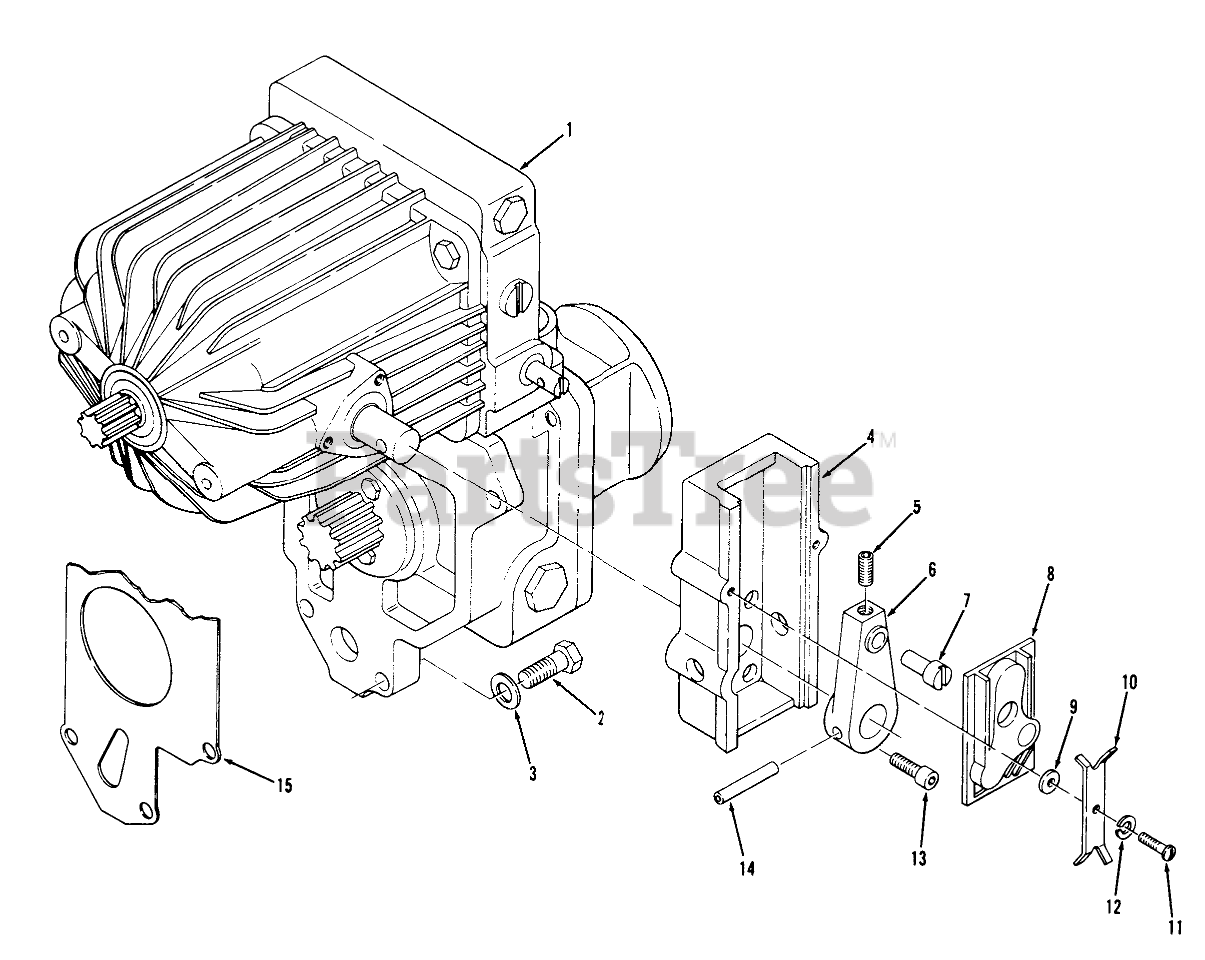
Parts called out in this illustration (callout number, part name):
1	Hydro Unit
2	BOLT
3	Washer
4	SUPPORT CAM BLOCK
6	Belt Guide
7	ECC CAM FOLLOWER
8	CAM
9	WASHER
10	TENSION PLATE
11	SCREW
12	LOCKWASHER
13	SHCS 1/4-20 X 1/2
14	PIN-ROLL 1/4 X 1 1/4
15	GASKET
